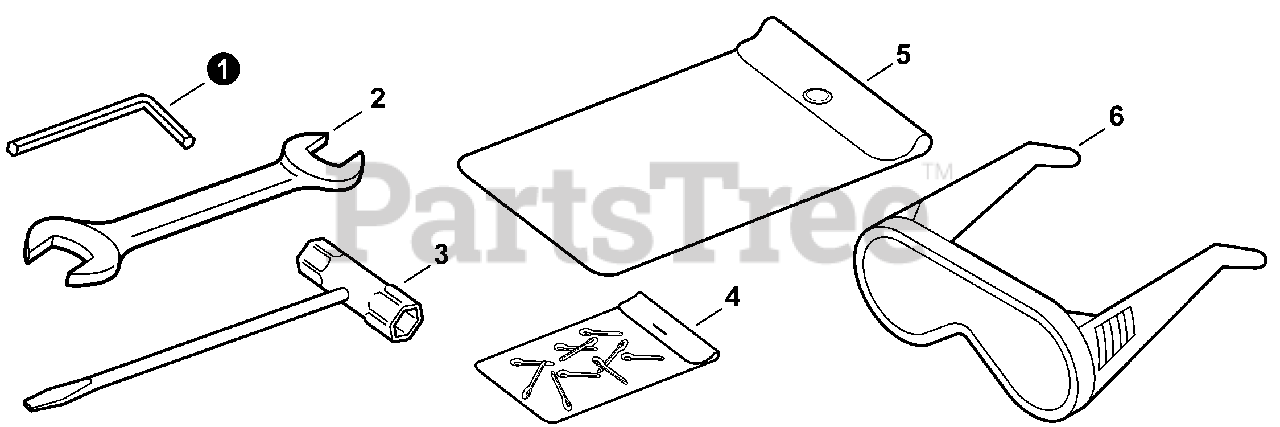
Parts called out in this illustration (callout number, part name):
1	WRENCH, ALLEN 4MM
2	SPANNER 8×10
3	T-WRENCH 17×19 L200
4	PIN, COTTER 2×22
5	BAG, TOOL
6	GLASSES, SAFETY
